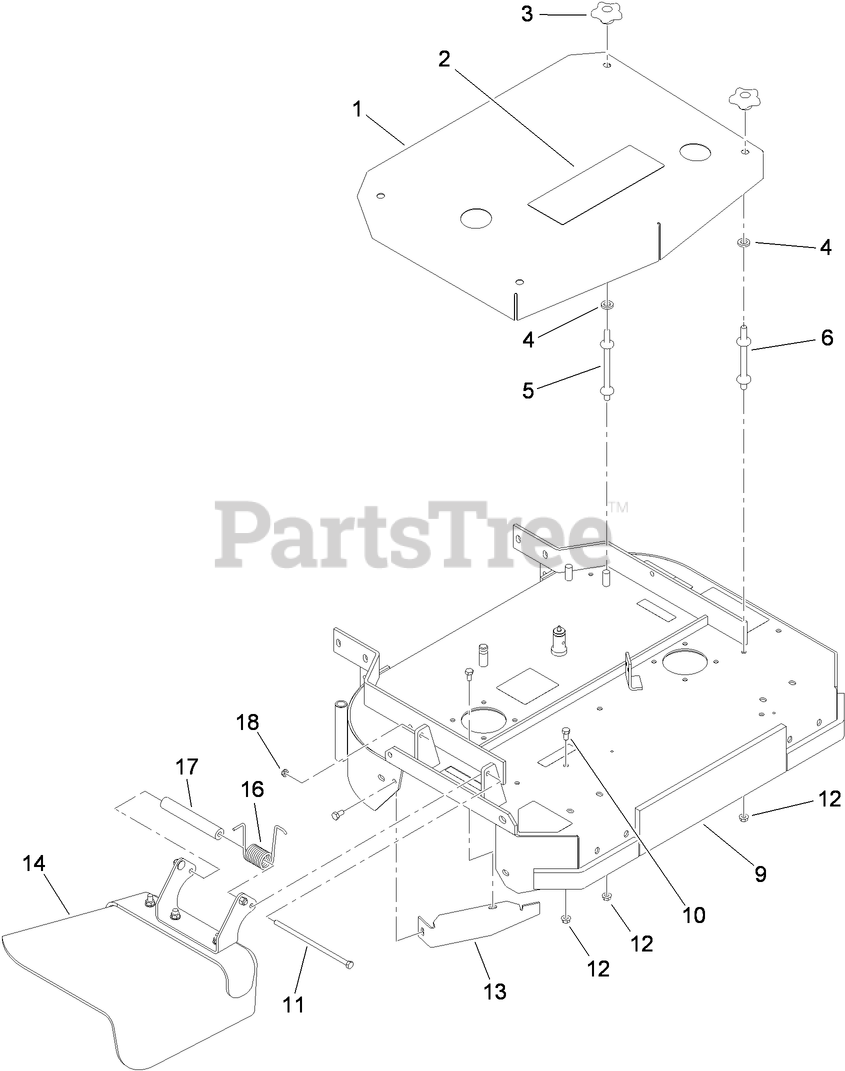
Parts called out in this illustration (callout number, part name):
1	SHIELD ASM
3	KNOB-HANDLE
4	WASHER
5	STUD-SHIELD, BELT (LONG)
6	STUD-SHIELD, BELT (SHORT)
9	32 INCH DECK ASM
10	SCREW-HH
11	SCREW-HH
12	NUT-HF
13	BAFFLE-DOGLEG
14	DEFLECTOR ASM
16	SPRING-TORSION
17	SPACER
18	NUT-LOCK, NI
